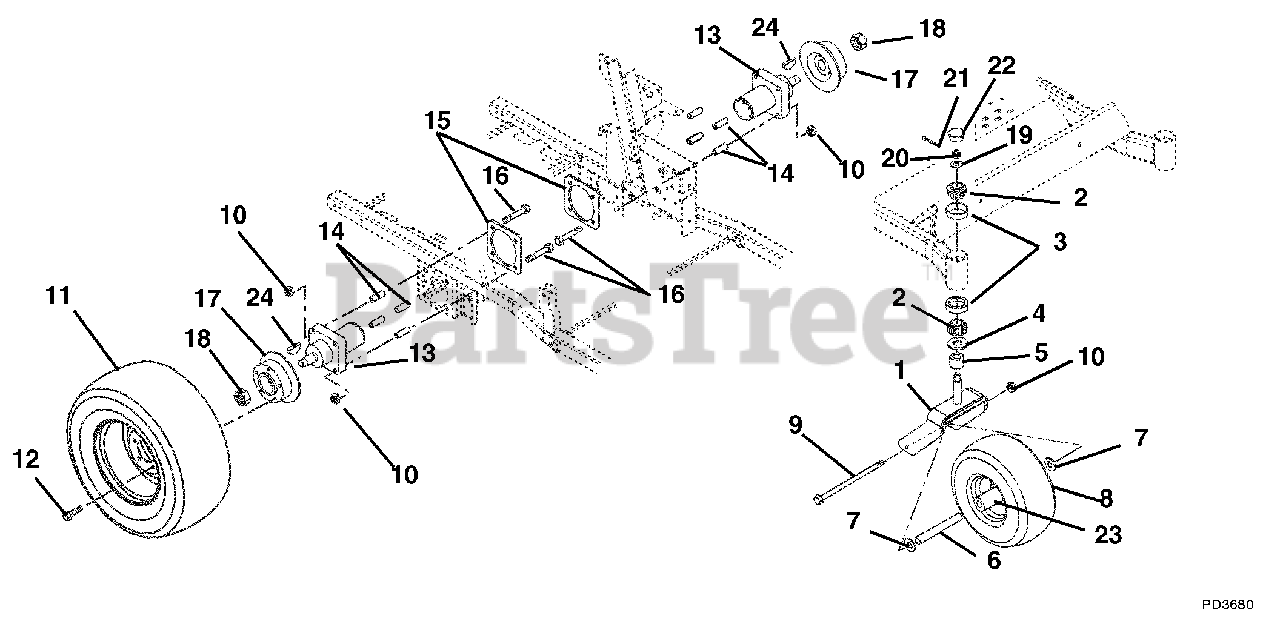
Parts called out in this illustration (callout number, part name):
1	Fork
2	Bearing-Cone w/ Grease
3	Bearing-Cup 1.980 x .420
4	Bearing Seal 1.5 x 2 x .18
5	Spacer, PM, 1.03 I.D. x 1.5 O.D. x .375
6	Spacer-Wheel
7	Washer-Flat-Steel .515 x 1.625 x .250
8	Wheel/Tire Assembly
8	Tire, 15 x 6-6
9	Bolt-Hex .50-13 x 9.00 Grade 5
10	Nut-Locking-Top-Flange .50-13
11	Wheel-Tire 23 x 10.50 - 12 Multi-Trac (043, 044, 054, 311)
11	Wheel-Tire Assembly 23 x 9 50-12 (042, 310)
11	Wheel-Tire Assembly, 23X10.50-12 (051, 054, 055)
11	Tire 23 x 10.50 (043, 044, 051, 054, 055, 311)
11	Tire, 23 x 9.50-12 Multitrac (042, 310)
12	Bolt-Lug Grade 8; .50-20 Unf x .75 Long 60 Degree
13	Hydraulic Wheel Motor
14	Bushing-Sleeve .513 x .748 x 2.13
15	Plate, Motor Support
16	Bolt-Hex .50-13 x 5.00 Grade 5
17	Hub and Disc
18	Nut -Lock Jam Patch
19	Washer-Flat-Steel .755 x 1.375 x .062
20	Nut-Slotted .75-16
21	Pin-Cotter .16 x 1.00
22	Cap-Dust
23	Bearing, 25MM I.D. x 52MM OD x 15MM
24	Key-Woodruff .31 x 1.00
